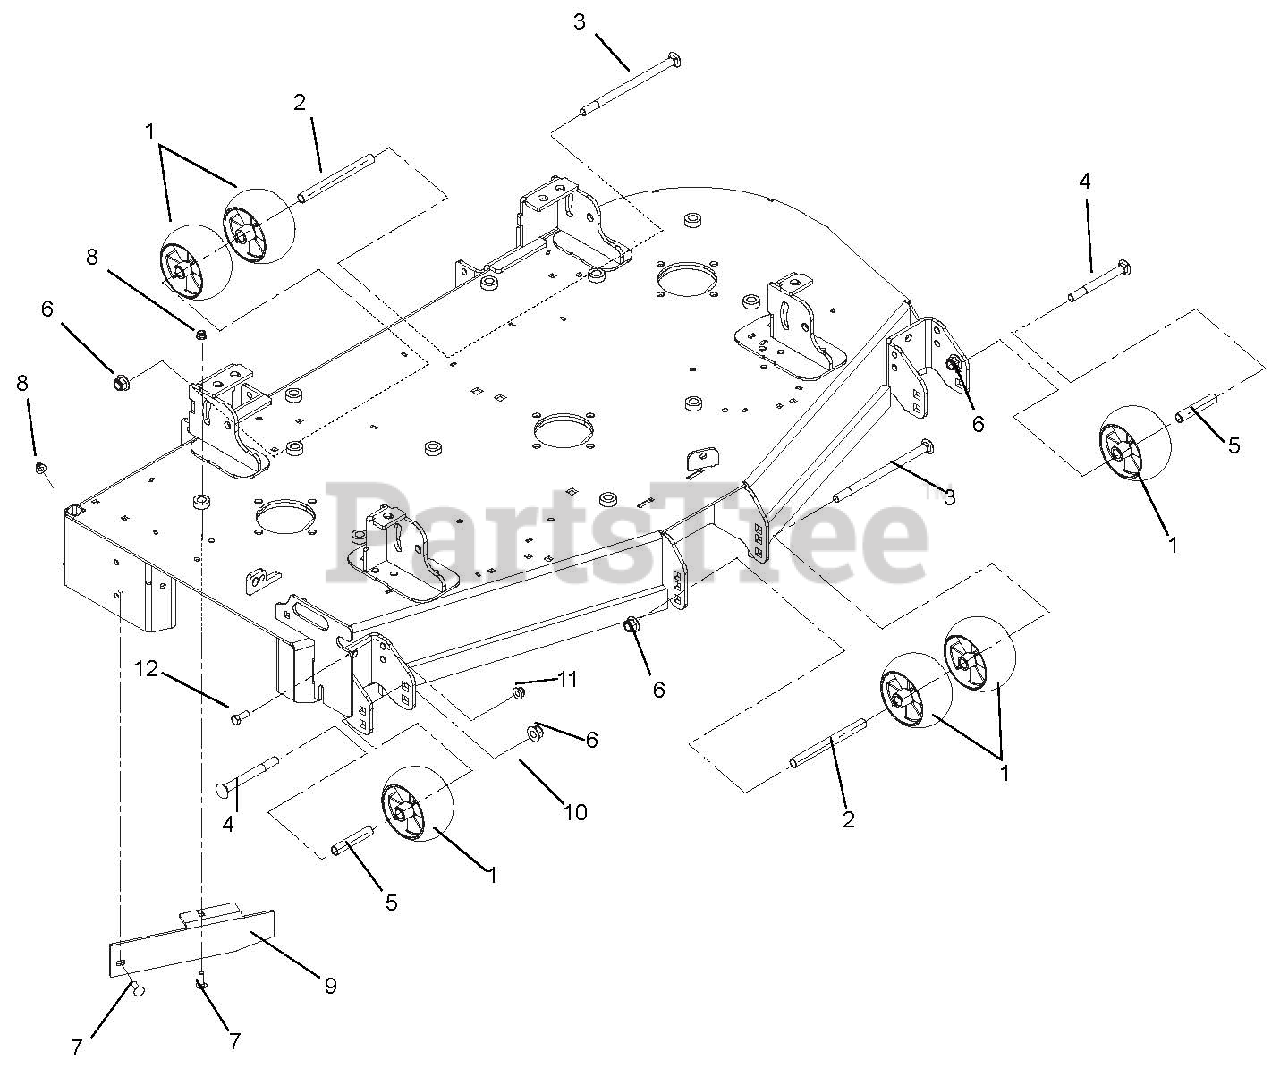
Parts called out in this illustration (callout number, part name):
1	Anti-Scalp Wheel, 5 x 3 Center
2	Spacer, .510 x .625 x 6.70
3	Bolt, Round Head Square Neck .50-13 x 8.50
4	Bolt, Round Head Square Neck .50-13 x 5.00
5	Spacer, .510 x .625 x 3.35
6	Nut, Locking Nylon Flange .50-13
7	Bolt, Round Head Square Neck .31-18 x 1.00 Grade 5
8	Nut, Locking Nylon Flange .31-18
9	60" Discharge Baffle
9	66" Discharge Baffle
9	52" Discharge Baffle
10	Bracket, Chute Storage
11	Nut, Locking Nylon Flange .38-16
12	Bolt, Hex .38-16 x 1.00 Grade 5
